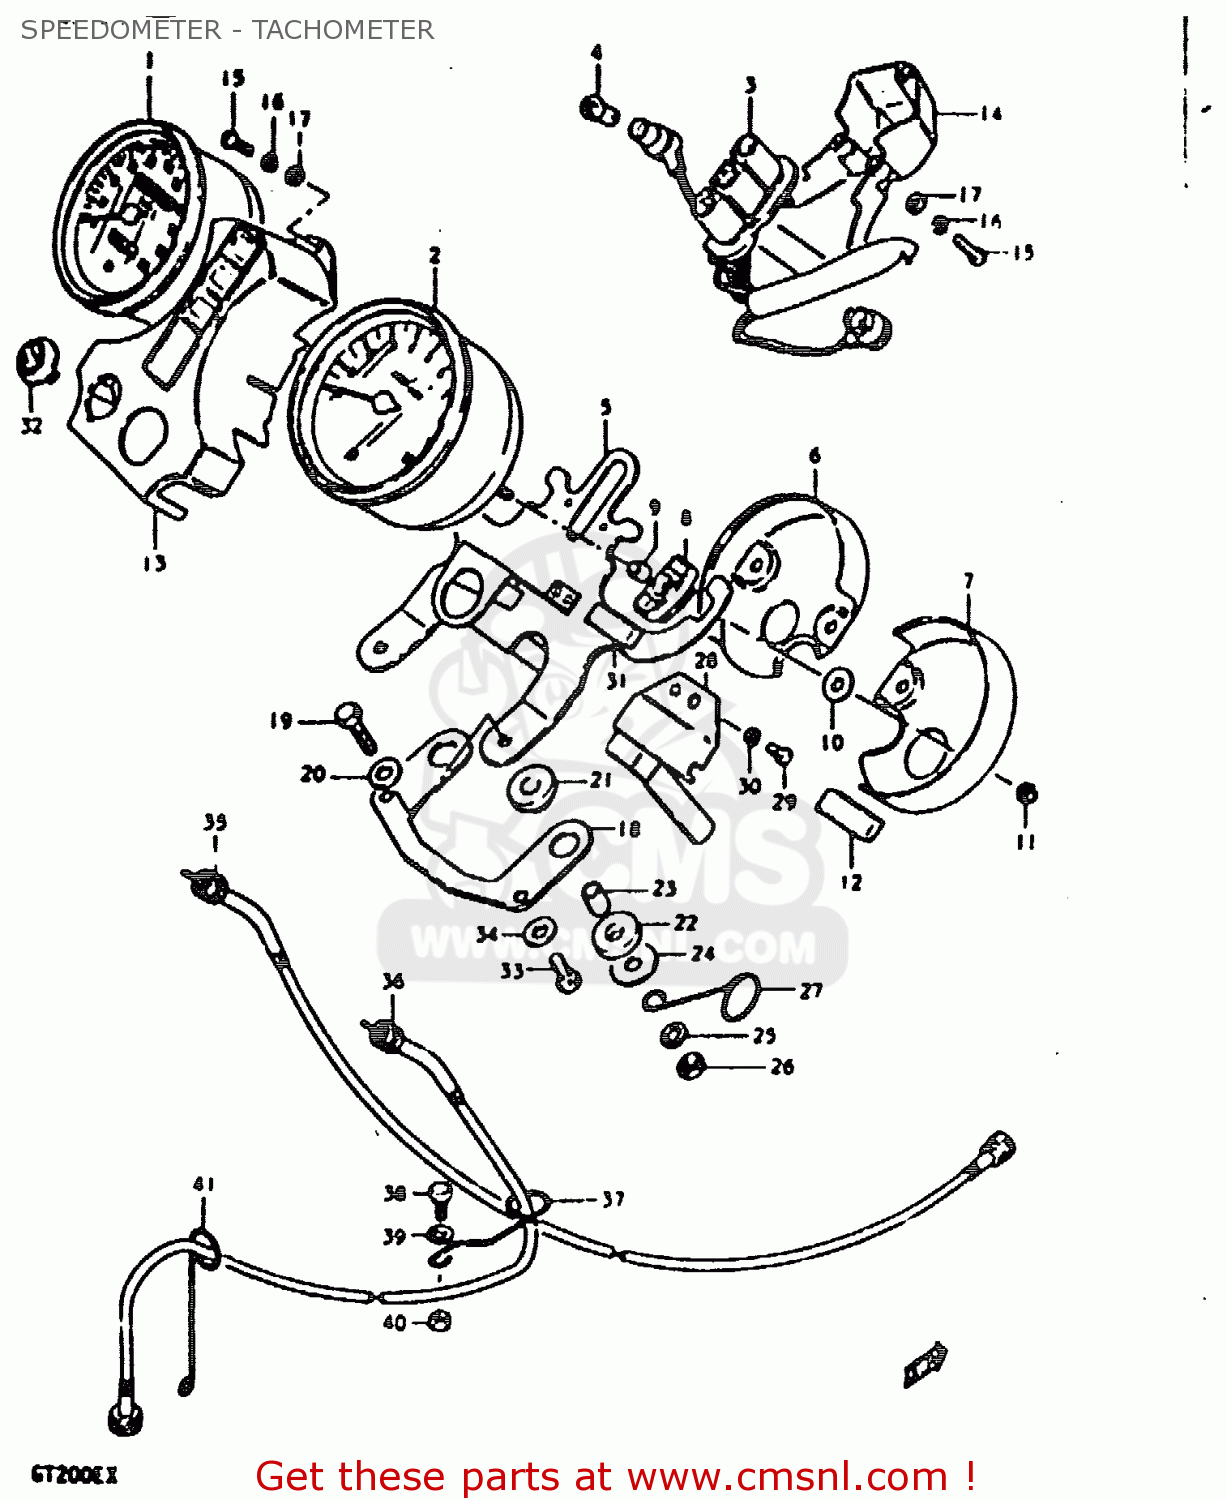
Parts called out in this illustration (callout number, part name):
1	SPEEDOMETER ASSY
2	TACHOMETER ASSY
3	SOCKET
4	BULB(12V3.4W,STANLEY,A72A)
5	BRACKET
6	UNDER COVER,SPEEDOMETER
7	UNDER COVER,TACHOMETER
8	CUSHION,METER
9	SPACER
10	WASHER (5.5X16X1.2)
11	NUT
12	CUSHION,METER
13	CASE, PILOT BULB
14	COVER
15	SCREW(4X16)
16	WASHER,PILOT UNDER CASE
17	WASHER
18	BRACKET
19	BOLT
20	WASHER
21	CUSHION
22	CUSHION
23	SPACER
24	WASHER (6.5X24X1.6)
25	LOCK WASHER
26	NUT
27	CLIP
28	HOLDER,COUPLER
29	SCREW 4X6
30	LOCK WASHER
31	PAD
32	CAP,SPEED WARNER LAMP HOLE
33	BOLT, UPPER
34	WASHER
35	CABLE, SPEEDOMETER
36	CABLE, TACHOMETER
37	GUIDE, TACHOMETER CABLE
38	BOLT
39	WASHER
40	NUT
41	GUIDE, TACHOMETER CABLE
